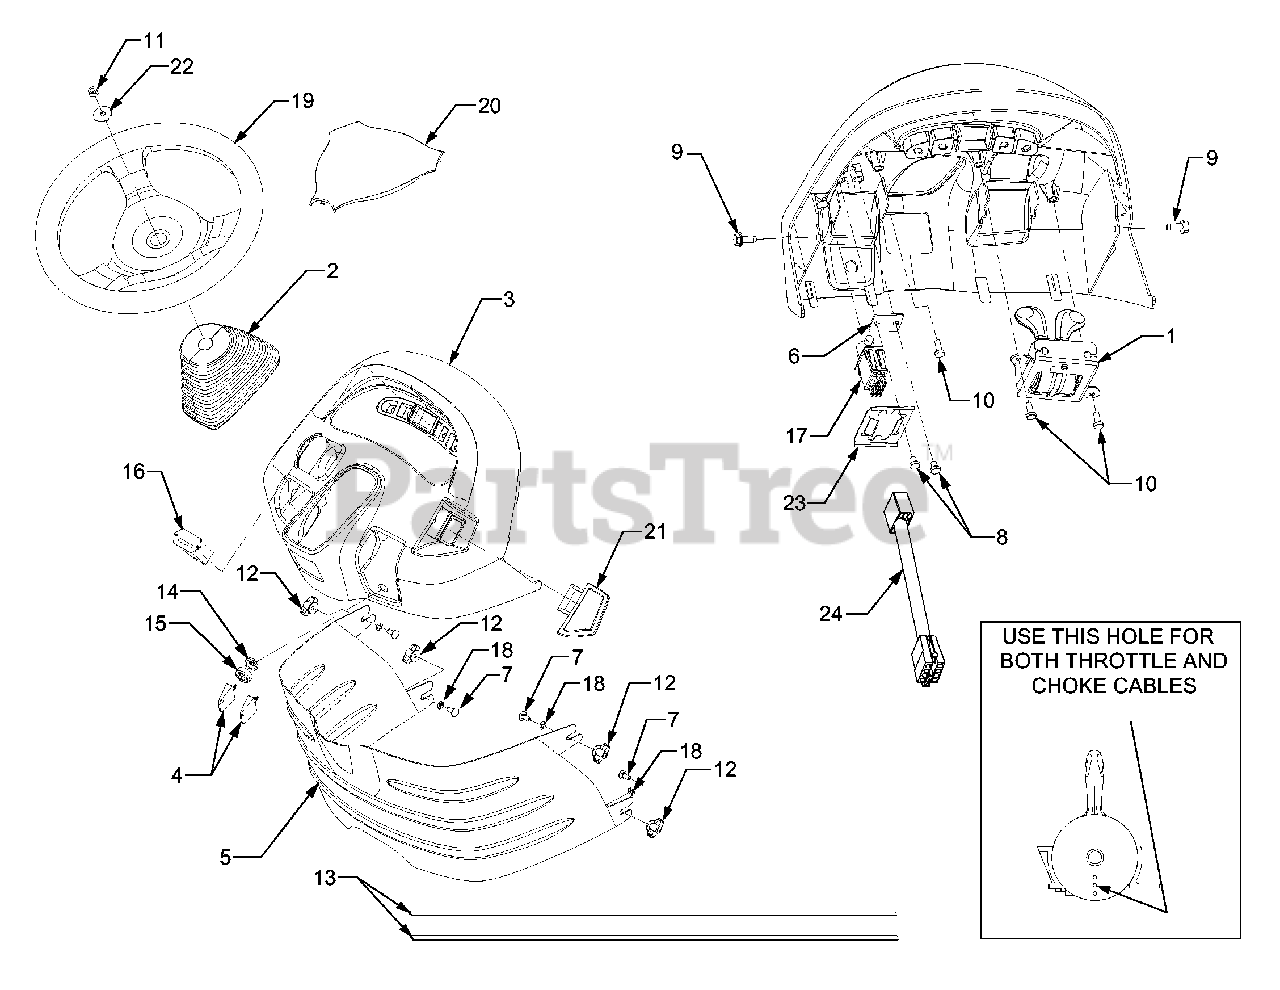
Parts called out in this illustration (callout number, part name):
1	Control Assembly, Throttle/Choke
2	Boot, Tilt Steer
3	Dash Panel
4	Key, Ignition (Set of 2)
7	Carriage Bolt, 1/4-20 x .62
8	Screw, Hex Cap 1/4-20 x .375 GR5
9	Screw, Hex Wash. Hd. Tapp 5/16-18 x .75
10	Screw, Hex Cap 1/4-20 x .50 GR5
11	Nut, Hex Lock, 5/16-24
12	Wing Nut, 1/4-20 w/Bell Washer
13	Seal, Screen Cut to fit screen
14	Nut, Ignition Switch, 5/8-32
15	Cap, Ignition Switch
16	Hour Meter
17	Switch, PTO
18	Nut, Push
19	Steering Wheel
20	Cover, Steering Wheel
21	Handle, PTO Switch
22	Washer, Flat, .34 x 1.5 x .10
23	Bracket, PTO Switch Retainer
24	Harness, PTO Adapter
